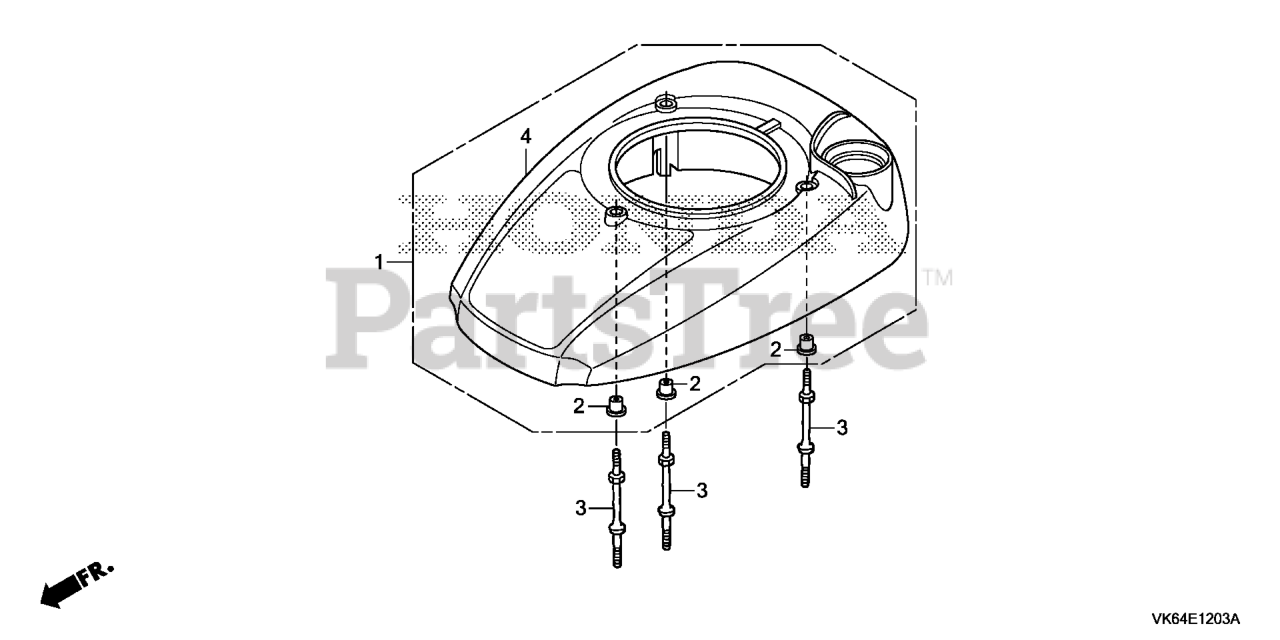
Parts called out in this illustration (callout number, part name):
1	COVER, FAN *R280* (POWER RED)
2	COLLAR, FAN COVER (Honda Code 5580527). (N/A: SEE ASSEMBLY)
3	BOLT, STUD
3	BOLT, STUD (FAN COVER)
4	COVER, FAN *R280* (POWER RED)
